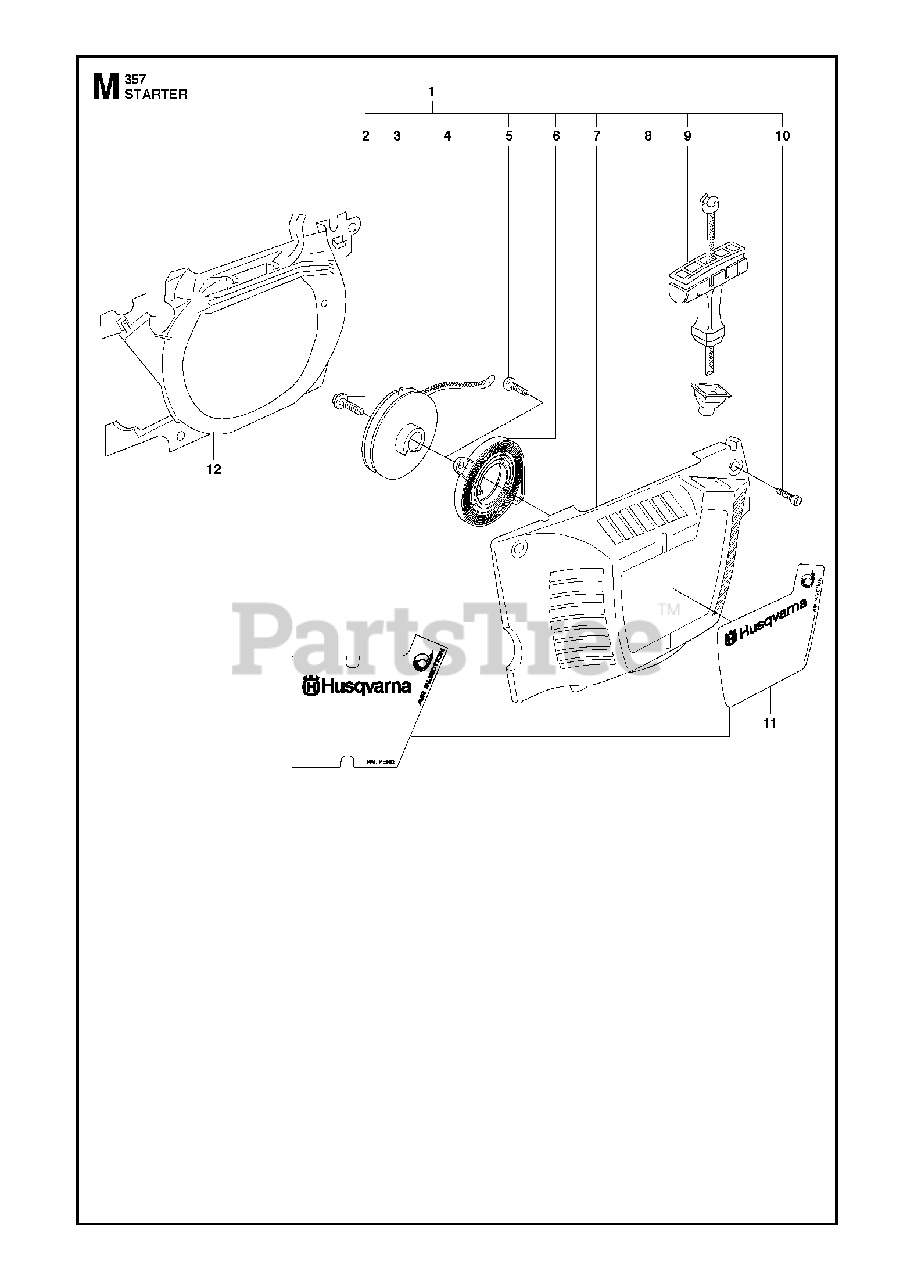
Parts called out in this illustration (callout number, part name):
1	STARTER DEVICE COMPLETE
2	SCREW
3	STARTER PULLEY
4	STARTER ROPE
5	SCREW
6	RETURN SPRING
7	STARTER HOUSING.
8	SLEEVE
9	STARTER HANDLE
10	SCREW
11	DECAL
11	Decal
12	AIR CONDUCTOR
